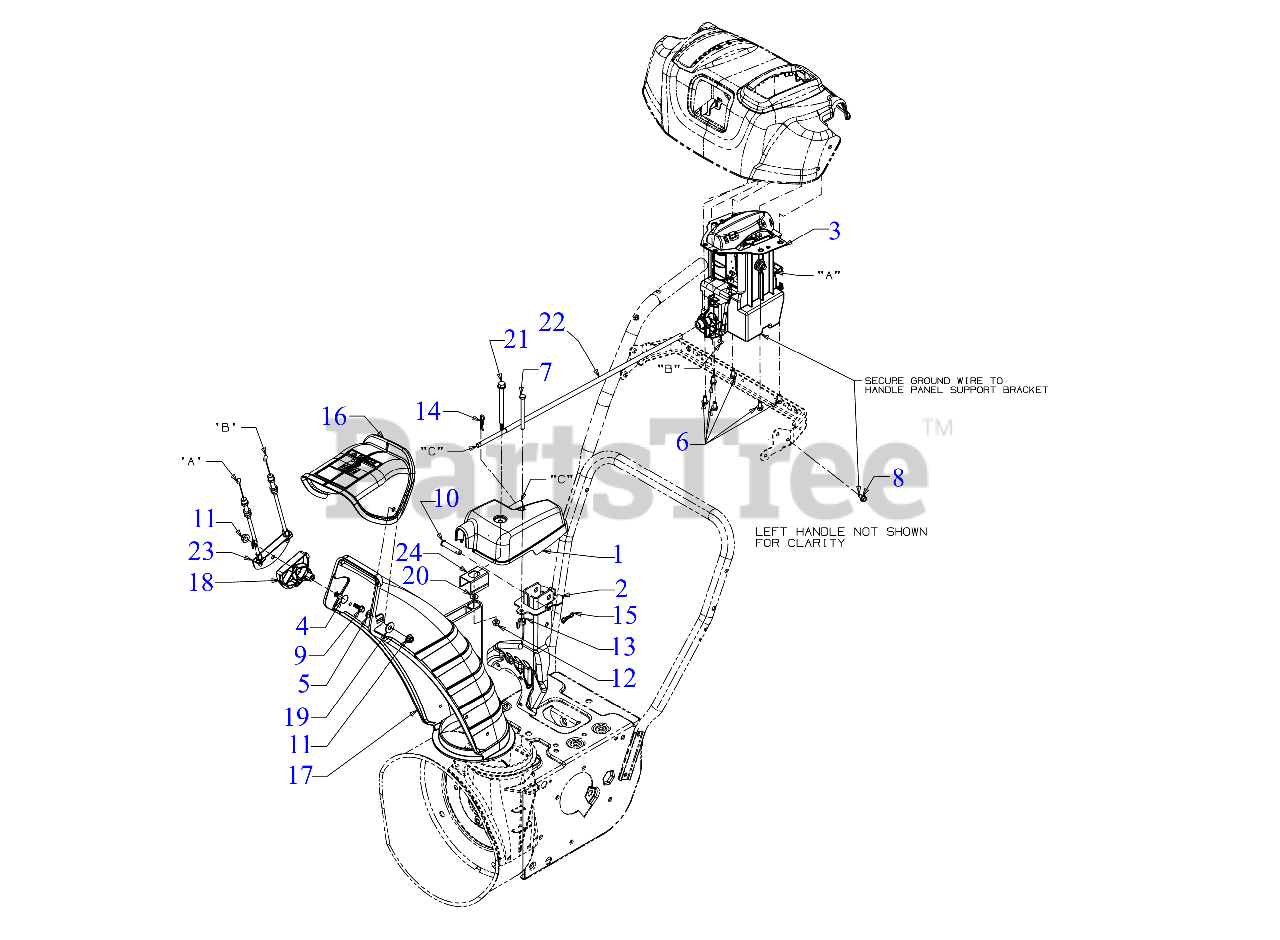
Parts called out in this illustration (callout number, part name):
1	WORM GEARBOX ASSEMBLY
2	CHUTE SUPPORT BRACKET (POWDER BLACK)
3	CHUTE CONTROL ASSEMBLY-4-WAY ELECTRIC
4	CARRIAGE BOLT 5/16-18 x 1.50
5	CARRIAGE BOLT 5/16-18 x 1
6	HEX SCREW 1/4-15 x .50
7	SCREW 1/4-20 x 3.0 GR5
8	SCREW 1/4-20 X.500
9	SCREW 1/4-15 x .750
10	CLEVIS PIN 3/8 x 1.87
11	FLANGE LOCK NUT 5/16-18
12	FLANGE LOCK NUT
13	WING NUT 1/4-20
14	INTERNAL COTTER PIN-1/2 DIA
15	BOW TIE COTTER PIN 1/4-5/16
16	UPPER REMOTE CHUTE WITH LABEL
17	LOWER CHUTE 5"
18	CABLE CHUTE GUIDE
19	FLAT WASHER
20	FLAT WASHER
21	SHOULDER SCREW
22	CHUTE CONTROL ROD .375"
23	CABLE BRACKET (POWDER BLACK)
24	CHUTE BRACKET
